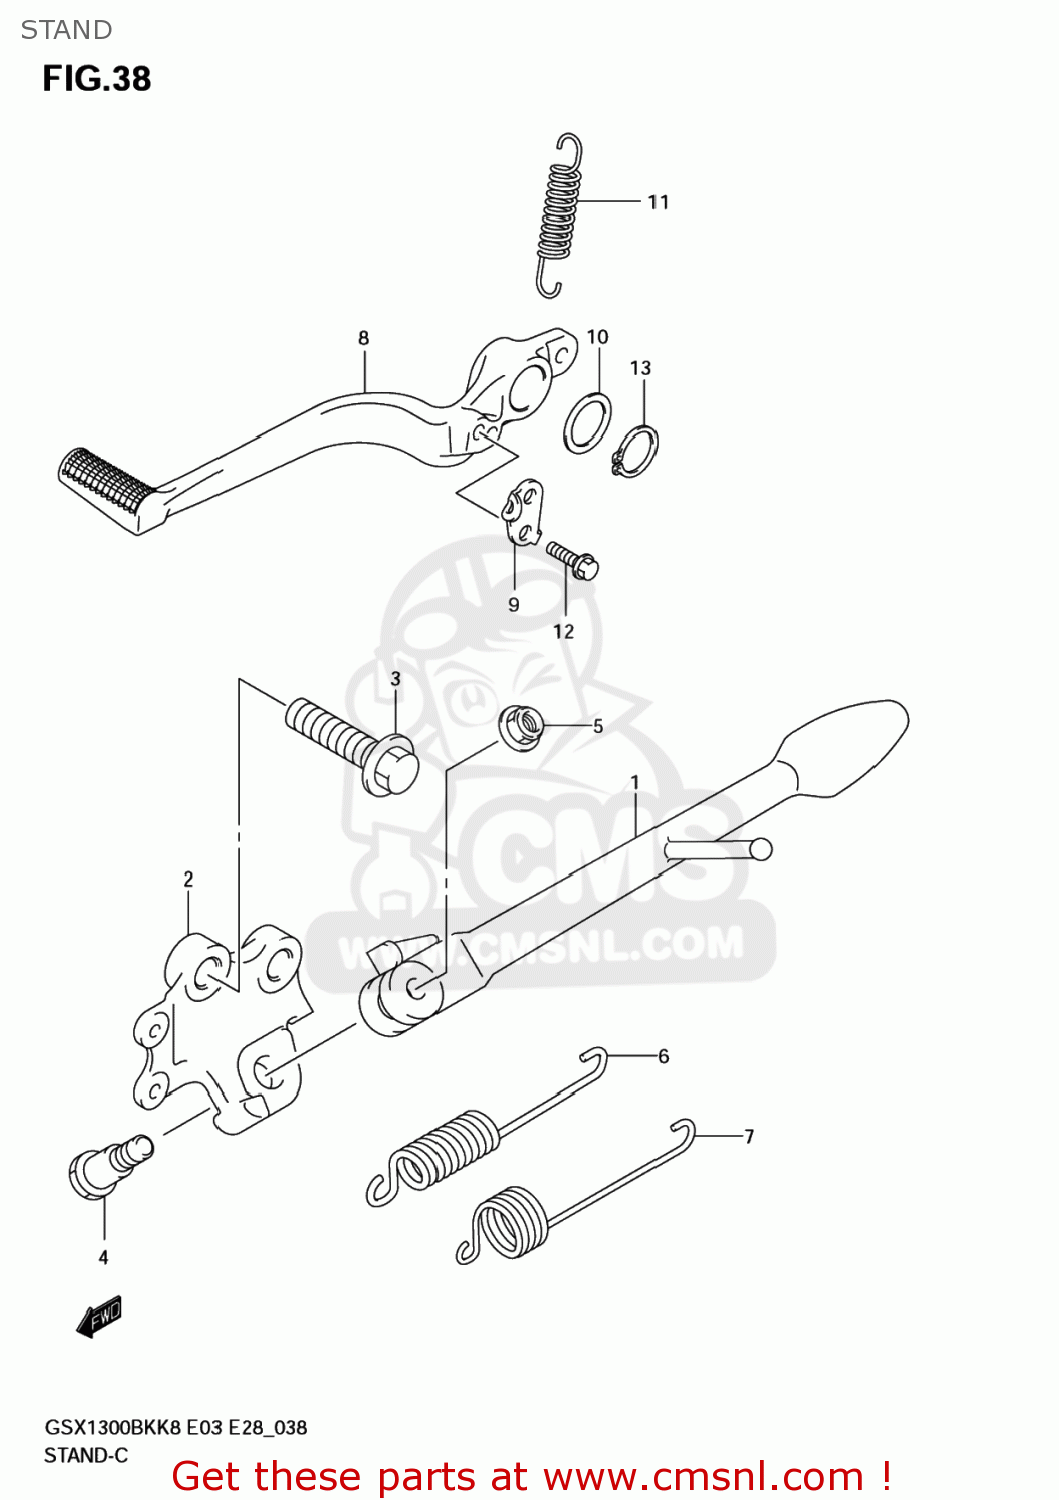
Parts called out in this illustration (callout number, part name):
1	STAND,PROP
2	BRACKET,PROP STAND
3	BOLT(12X35)
4	BOLT(10X21)
5	NUT
6	SPRING
7	SPRING
8	PEDAL,BRAKE
9	PLATE,RETURN SPRING
10	WASHER(18X24X1)
11	SPRING
12	BOLT
13	CIRCLIP
